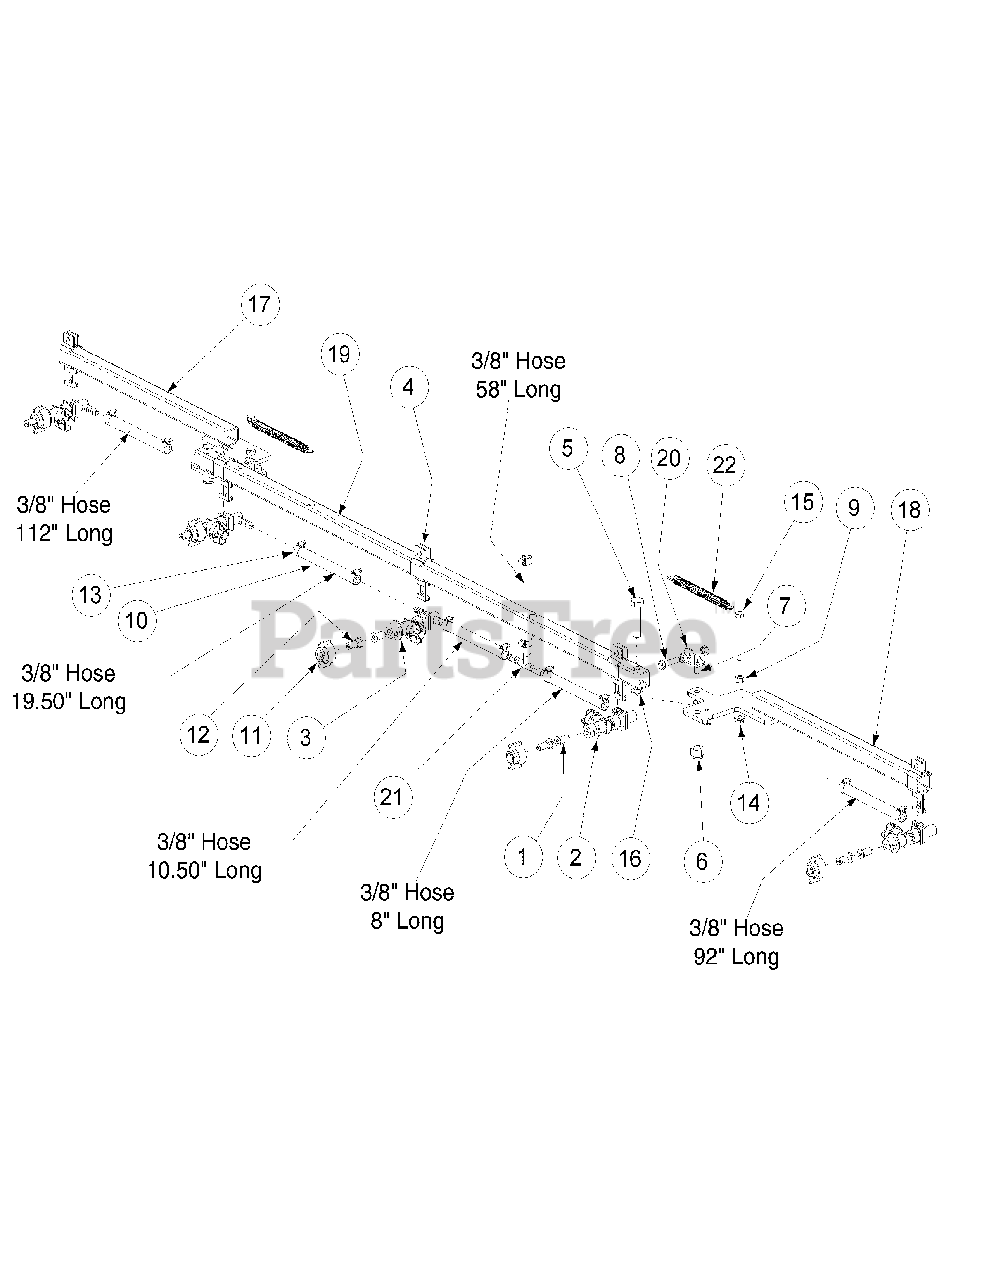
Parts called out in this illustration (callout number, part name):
1	Strainer Screen, 50 Mesh, SS
2	Nozzle, Single Body, Dry Boom
3	Nozzle, Double Body, Dry Boom
4	Clamp, Body Nozzle
5	HHCS, 1/2-13 x 2.00
6	Nut, 1/2-13
7	HHCS, 5/16-18 x 1.0
8	HHCS, 5/16-18 x 1.25
9	Nut, 5/16-18
10	Hose, 3/8"
11	Cap
12	Nozzle, Turbo Flood Jet
13	Hose Clamp
14	Nut, Lock, HexFlange, 5/16-18
15	HHCS, 5/16-18 x 2.75
16	Washer, .50 ID x .75 OD x .031
17	Boom Arm Assembly, RH
18	Boom Arm Assembly, LH
20	Boom Stop Arm
21	T-Fitting, 3/8
22	Extension Spring
